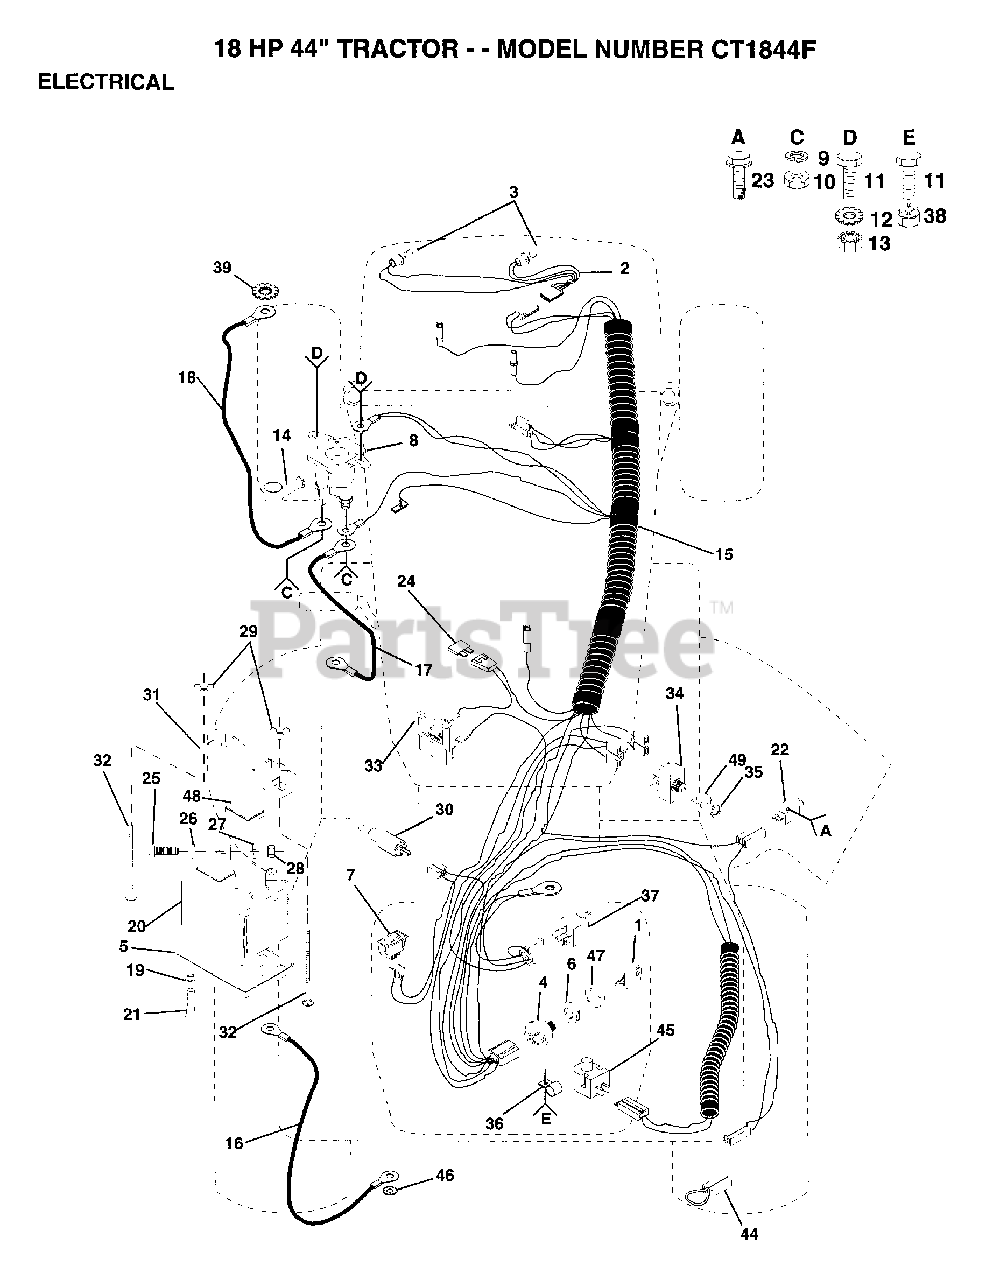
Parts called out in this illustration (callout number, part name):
1	KEY
2	"HARNESS,LIGHT SOC"
5	"TRAY T, BATTERY"
6	NUT IGNITION
7	SWITCH LT
10	NUT
11	BOLT
13	NUT
15	HARNESS.IGN.B&S
16	CABLE T
17	CABLE-BATTERY T
18	"CABLE T, BATTERY"
19	HOSE CLAMP T
21	"DRAIN TU T, BATT"
22	SWITCH-INTER. GT
23	SCREW
24	FUSE HYT
25	BOLT LT
26	WASHER
27	LOCKWASHER
30	DIODE ASM.
32	BOLT
34	"SWITCH,PTO"
35	HEX NUT T
36	CLIPT
37	RELAY ASSY T
39	LOCKWASHER
45	SWITCH SEAT
46	LOCKWASHER
48	"CAP,BATTERY "
49	WASHER
